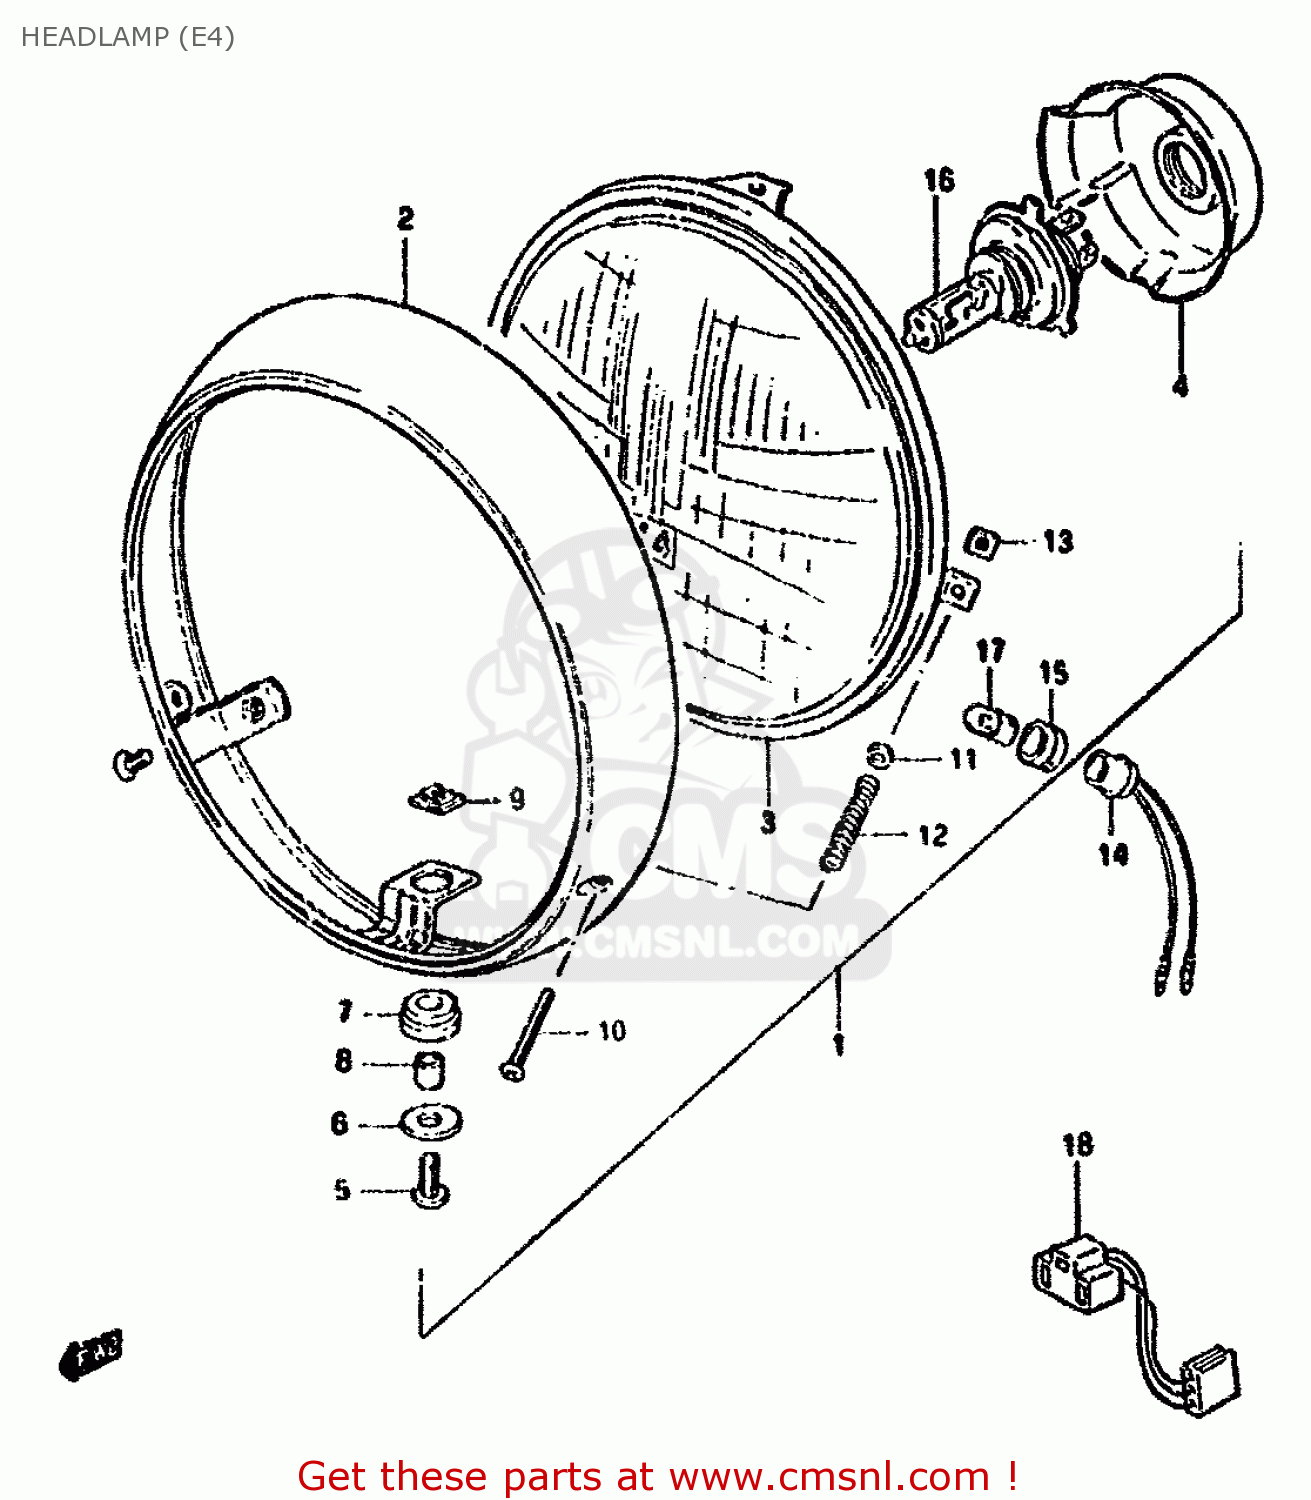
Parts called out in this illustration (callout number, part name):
1	HEADLAMP ASSY
2	RIM
3	LAMP UNIT
4	COVER,SOCKET
5	SCREW
6	WASHER
7	CUSHION
8	SPACER
9	NUT
10	SCREW
11	WASHER
12	SPRING
13	NUT,HEADLAMP ADJUSTER
14	SOCKET
15	JOINT,RUBBER
16	BULB(12V60/55W,H4)
17	BULB
18	SCREW
